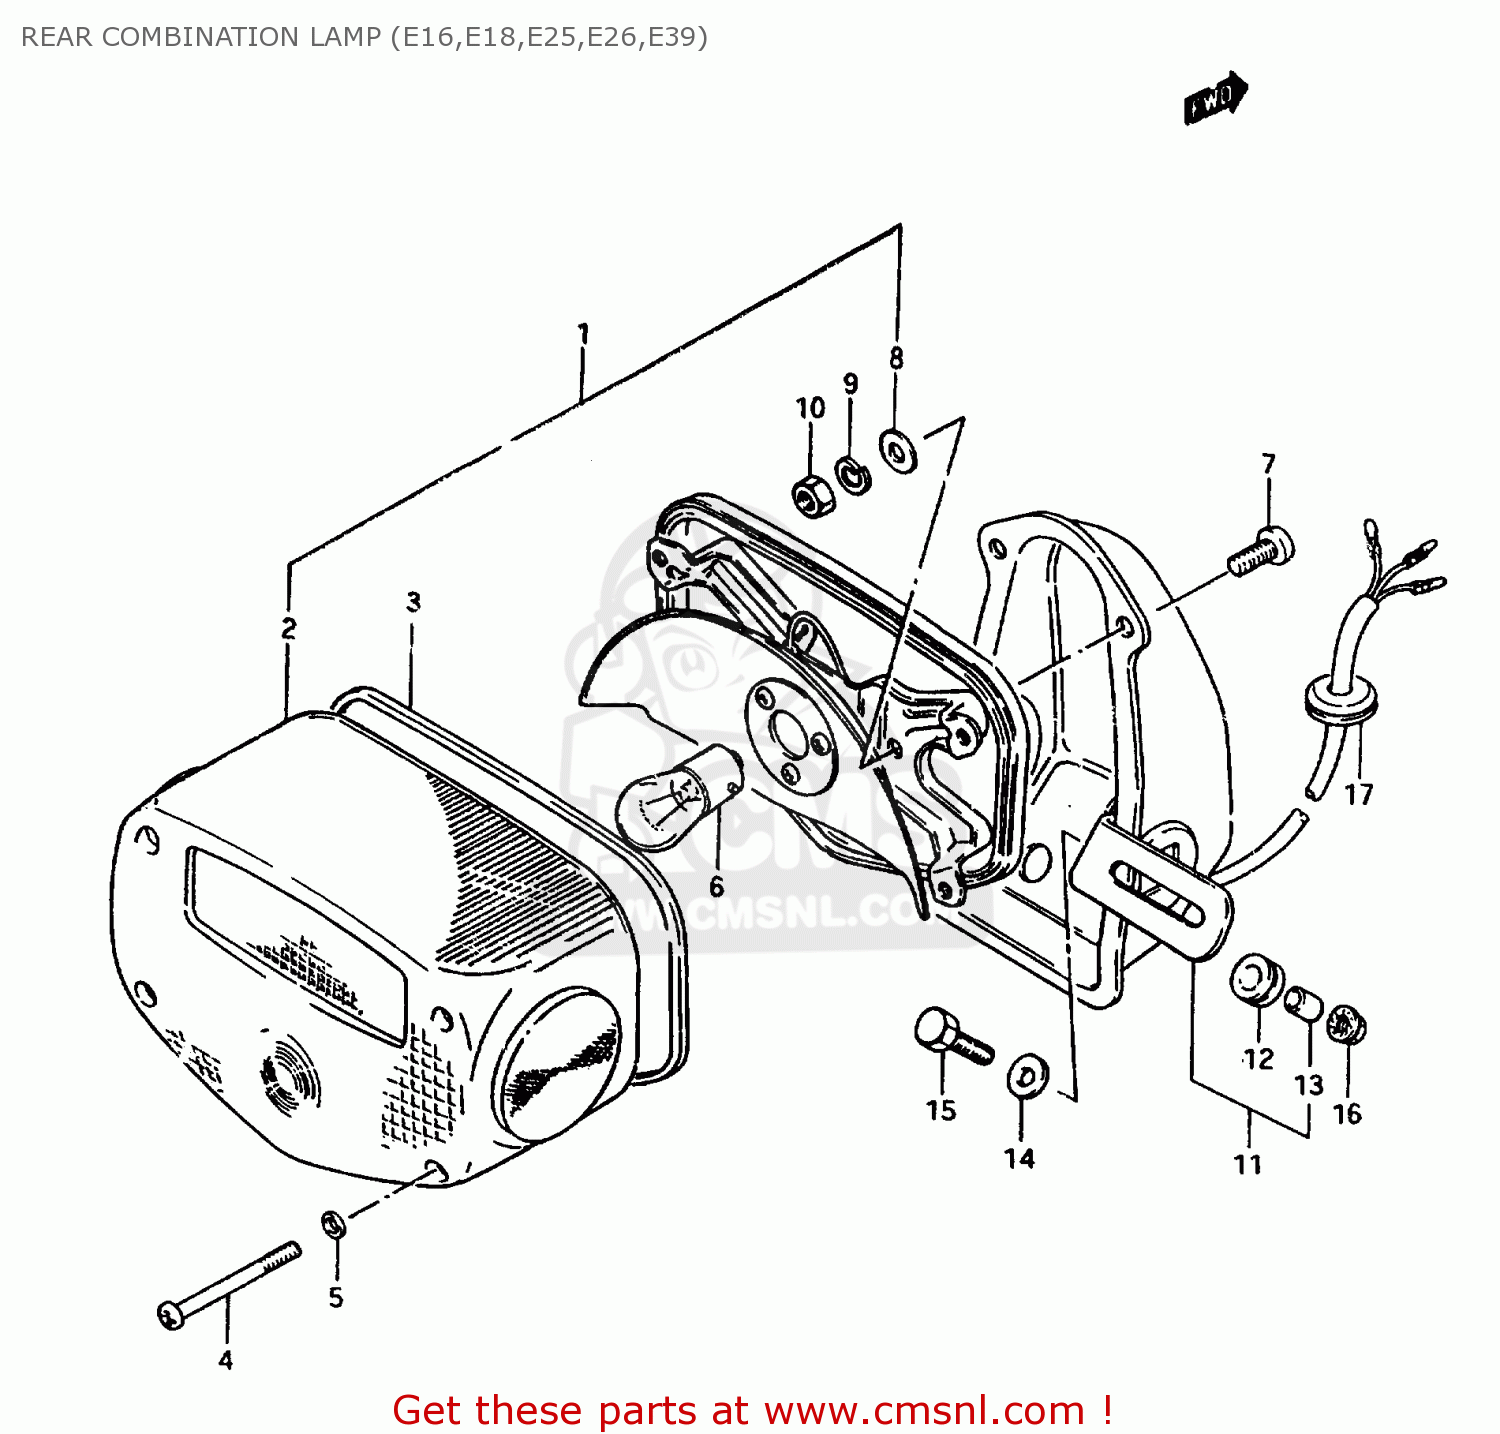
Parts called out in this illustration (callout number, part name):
1	LAMP UNIT, REAR COMBINATION
2	LENS
3	GASKET (NAS)
4	SCREW (4X55)
5	GASKET (NAS)
6	BULB(12V21/5W)
7	SCREW 6X12
8	WASHER
9	LOCK WASHER
10	NUT
11	BRACKET UNIT
12	CUSHION
13	SPACER
14	WASHER (6.5X20X1.2)
15	BOLT
16	NUT 6MM
17	GROMMET
